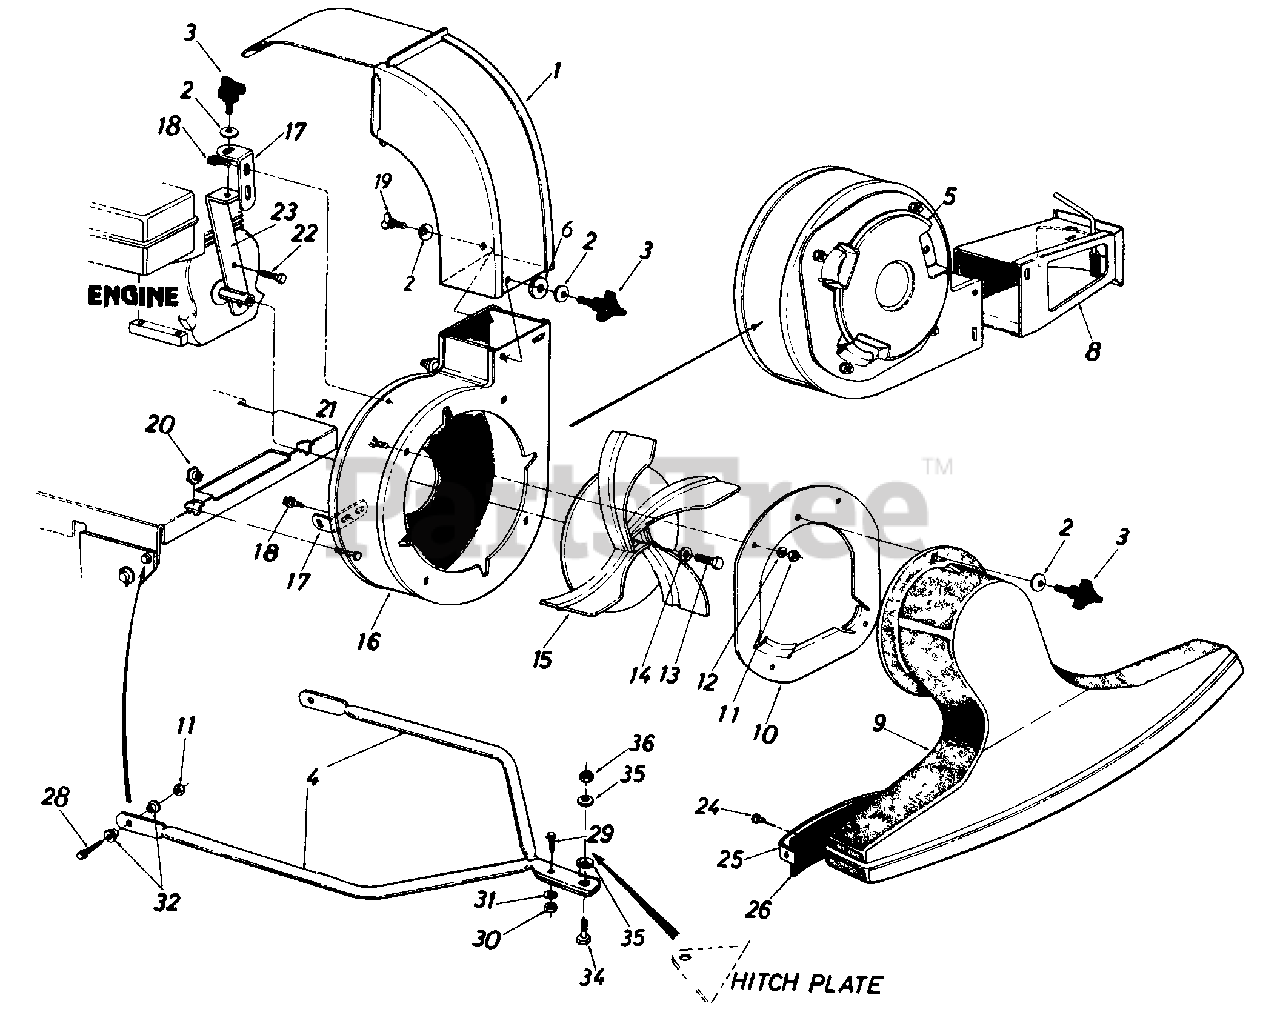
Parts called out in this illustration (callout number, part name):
3	Hand Knob
6	Fl-Wash. .344" I.D. x 1.125" O.D.
10	Nozzle Plate Ass'y.
11	Hex Nut 5/16-18 Thd.
12	L-Wash. 5/16" I.D.
13	Hex Bolt 3/8-24 x 1.25" Lg.
14	L-Wash. 3/8" I.D. H.D.
15	Air Vane Plate Ass'y. w/Pulley
19	Thumb Screw 5/16-18
20	Hex Shoulder Nut .50 I.D.
21	Carriage Bolt 5/16-18 x .62"
22	Hex Locking Bolt 5/16-24 x .75 Lg.
28	Hex Bolt 5/16-18 x 1.00 Lg
29	Truss Mach. Scr. 1/4-20 x 75"
30	Hex Nut 1/4-20 Thd
31	L-Wash. 1/4" I.D.
32	Shoulder Spacer
34	Shld. Bolt .496 Dia
35	Belleville Wash. .39" I.D. x 1.12" O.D.
36	Hex Jam L-Nut 3/8-26 Thd.
